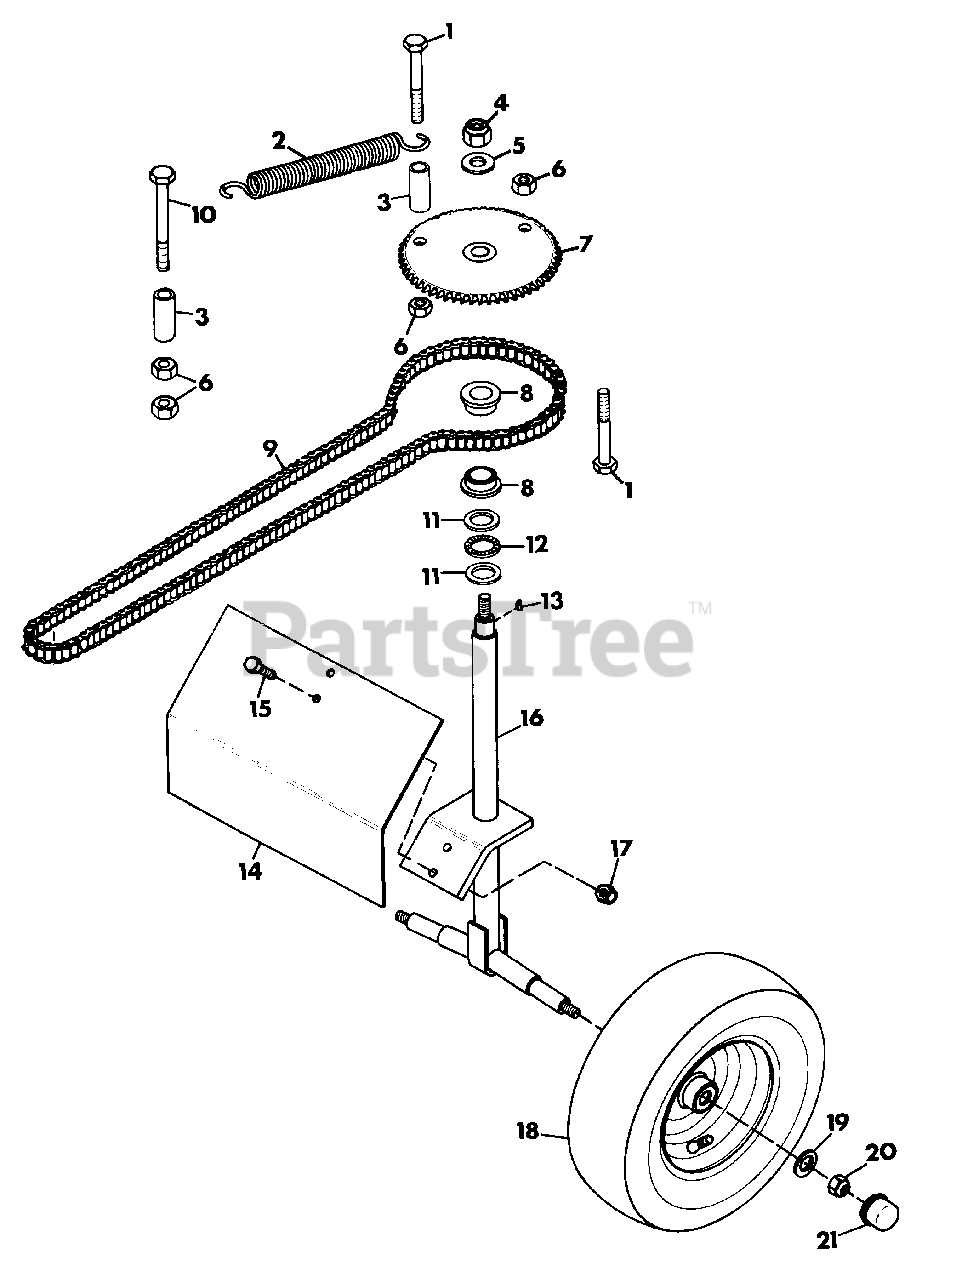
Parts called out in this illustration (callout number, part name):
1	BOLT, HEX 1/2-13X3.25
2	SPRING
3	BUSHING, MOWER PIVOT
4	NUT, LOCK 7/8-9
5	WASHER, FLAT .969X2.250X.165
6	NUT, HEX 1/2-13
7	SPROCKET, 60T #40
8	BEARING, FLANGED
9	CHAIN, OFC
10	BOLT, HEX 1/2-13X3.75
11	BEARING, THRUST RACE
12	BEARING, NEEDLE THRUST
13	KEY, WOODRUFF .250X.875 HARD #A
14	FENDER, PRO MASTER
15	BOLT, 1/2-13X1.25
16	WELDMENT, PRO MASTER AXLE
17	NUT, LOCK 1/2-13
18	WHEEL, REAR PRO MASTER
19	WASHER, FLAT .938X1.750X.134
20	NUT, LOCK 3/4-10
21	CAP
